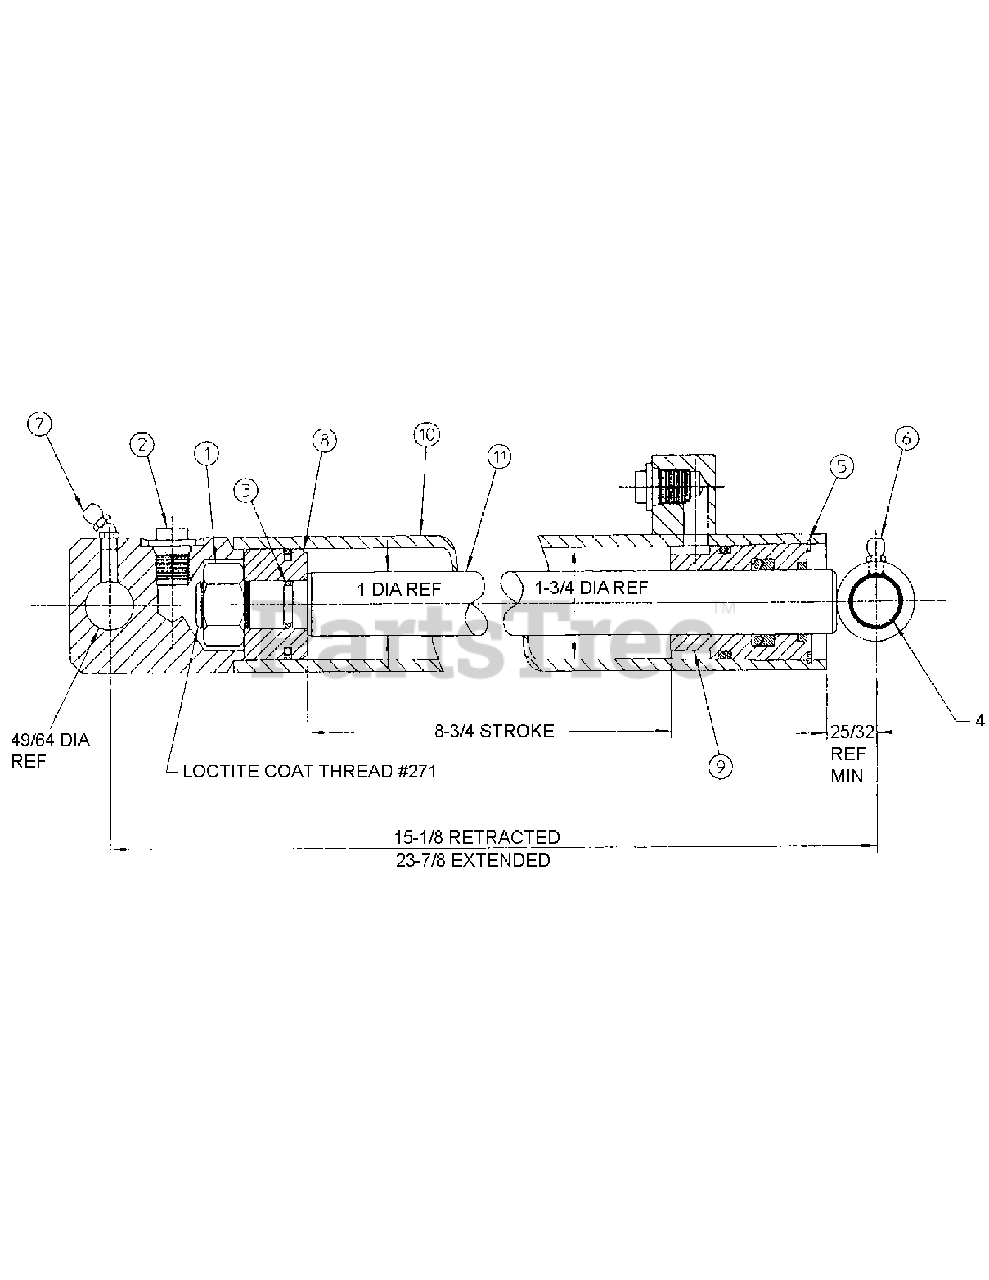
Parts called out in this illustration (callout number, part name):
1	Nut, 3/4" NF Lock
3	O-Ring*
4	Bronze Bearing 7/8"OD x 3/4"ID x 1" long
5	Retaining Ring
6	Grease Fitting, 1/4-28 Self Tapping
7	Grease Fitting, 1/4-28 Self Tapping x 45 degree
8	Piston Assembly with O-Ring
9	Gland with O-Ring, Back-Up Ring, etc.
10	Cylinder Tube Weldment
11	Piston Rod Weldment with Bronze Bearings
